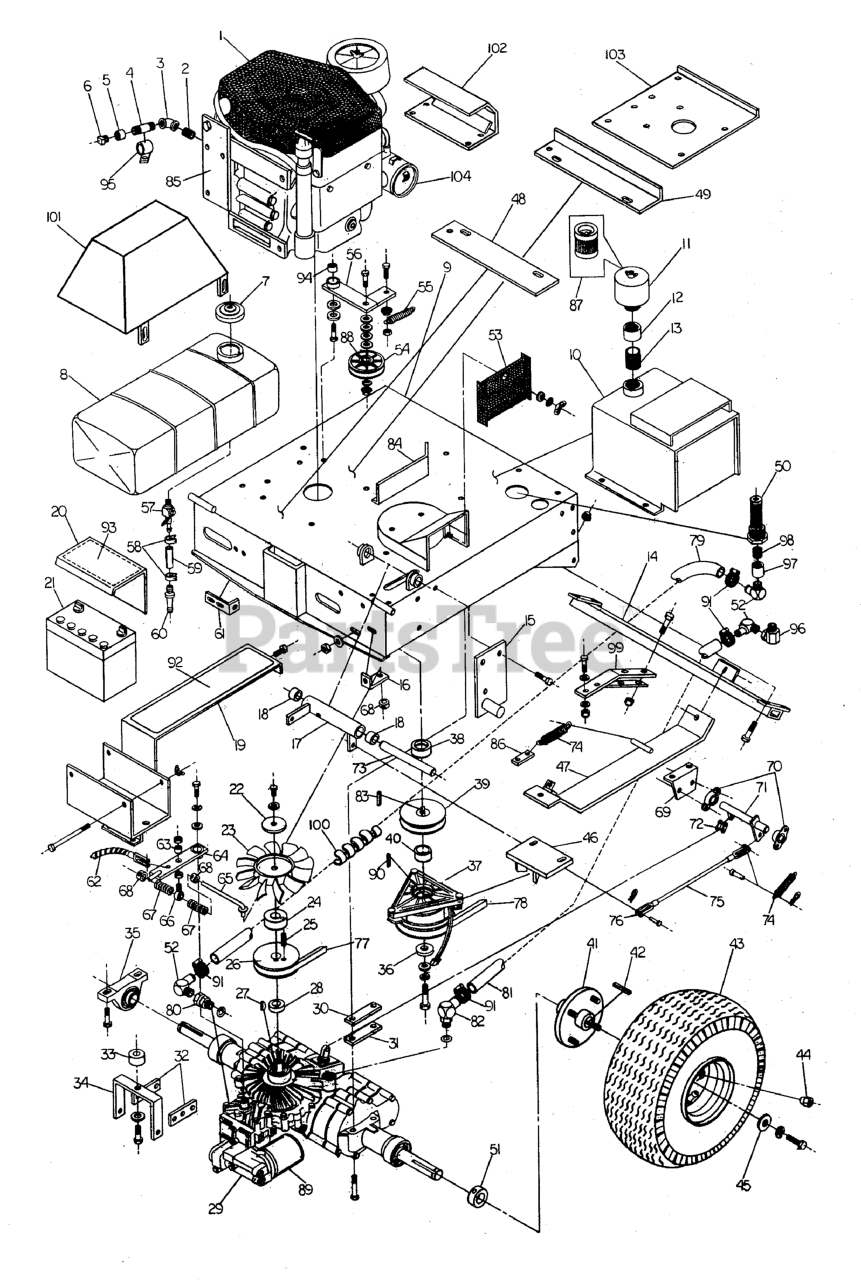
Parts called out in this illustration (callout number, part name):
2	Close Nipple
3	Elbow 45 Degree
4	Pipe Nipple
5	Coupler
6	Pipe Plug
7	Gas Cap
8	Fuel Tank, 4 Gallon
8	Gas Tank Strap
9	Engine Deck
9	Engine Deck (Onan)
10	Hydro Tank
11	Air Filter Assembly
12	1" Coupler
13	Close Nipple
14	Engine Deck Cross Member
15	Pivot Bracket - LH
15	Pivot Bracket - RH
16	Spring Anchor
17	Parking Brake Bell Crank
18	BUSHING, Brass
19	Gas Tank Mount
20	Battery Cover
21	BATTERY, Lawn & Garden, 12V (BCIU1, 340 CCA)
22	5/16 Fender Washer
24	Fan Pulley Spacer
25	Roller Pin
26	PULLEY (3/4" Bore)
27	KEY, #61 Woodruff
28	Hydro Input Pulley Spacer
29	850 Transaxle
30	1/4" Spacer (Red)
31	3/16" Spacer (Black)
32	BRACKET, Transmission Support
33	SPACER, .39 x 1.75 x .88
34	Transmission Torque Bracket
35	BEARING, PILLOW BLOCK, 1
36	SPACER, .45 x 1.62 x .37
37	CLUTCH, Electric, 1" Shaft
37	CLUTCH, Electric, 1-1/8" Shaft
38	SPACER, 1.13 X 1.75 X .88
39	PULLEY, Crankshaft
40	SPACER, 1.13 X 2.00 X .37
41	DRIVE HUB DETAIL
42	KEY, 1/4 SQ. X 2-1/2
43	TIRE & WHEEL ASSEMBLY, 18 X 8.5 X 8
43	WHEEL & TIRE ASSEMBLY, 20 x 10 x 8, Complete
44	LUG NUT, 1/2-20
45	Retaining Spacer
46	Electric Clutch Anchor
47	Skid Plate
48	Engine Support Rear
49	Engine Support Front
50	STRAINER
51	COLLAR, 1" Split
52	FITTING, 90 Degrees 1/2" NPT
53	Hydro Intake Screen
54	Idler Pulley
55	SPRING, Extension
56	IDLER ARM ASSEMBLY, Complete
57	Fuel Shut-Off Valve
58	CLAMP, Hose
59	Fuel Line
60	FUEL FILTER
61	CABLE BRACKET
62	CABLE, Speed Control
63	SPACER, .38 x .50 x .27
64	TRANSMISSION CONTROL ARM
65	ROD, NEUTRAL SPRING WELDMENT
66	BALL JOINT, 3/8-24 Male
67	SPRING, Compression
68	COLLAR, 5/16" Set
69	Bearing Mount Parking Brake
70	BEARING, Flange
71	Parking Brake Jackshaft
72	CONNECTOR, #50 Chain Link
73	3/4" Shaft
74	SPRING, Extension
75	Linkage Rod
76	CLEVIS, 5/16-24, Plastic
77	BELT, A-Section
78	BELT, B-Section
78	Belt 48" Deck
79	Inlet Hose
80	FITTING, 7/8" O-Ring Straight Swivel
81	Return Hose
82	FITTING, 90 Degrees 7/8" O-Ring
83	KEY, 1/4" SQ. X 1-1/4
84	Heat Deflector
85	Oil Filter Mount
86	Dump Valve Lever
87	Air Filter Element
88	INSERT, Bearing
89	FILTER, Transmission Oil
90	KEY, 1/4 SQ. X 1-1/4
91	CLAMP, #10 Hose
92	SAFETY WALK
93	SAFETY WALK
94	SPACER, .32 x .75 x 1.06
95	Oil Drain Hold Down
96	FITTING, 1/2 NPT Swivel, 90 Deg.
97	COUPLER, 1/2" NPT
98	NIPPLE, 1/2" NPT Close
99	Torque Arm
100	Plastic Hose Coil
101	Fender, LH
102	Muffler Guard
103	Engine Plate (Onan)
104	Muffler (Onan)
104	Manifold (Onan)
104	Muffler (Kohler)
